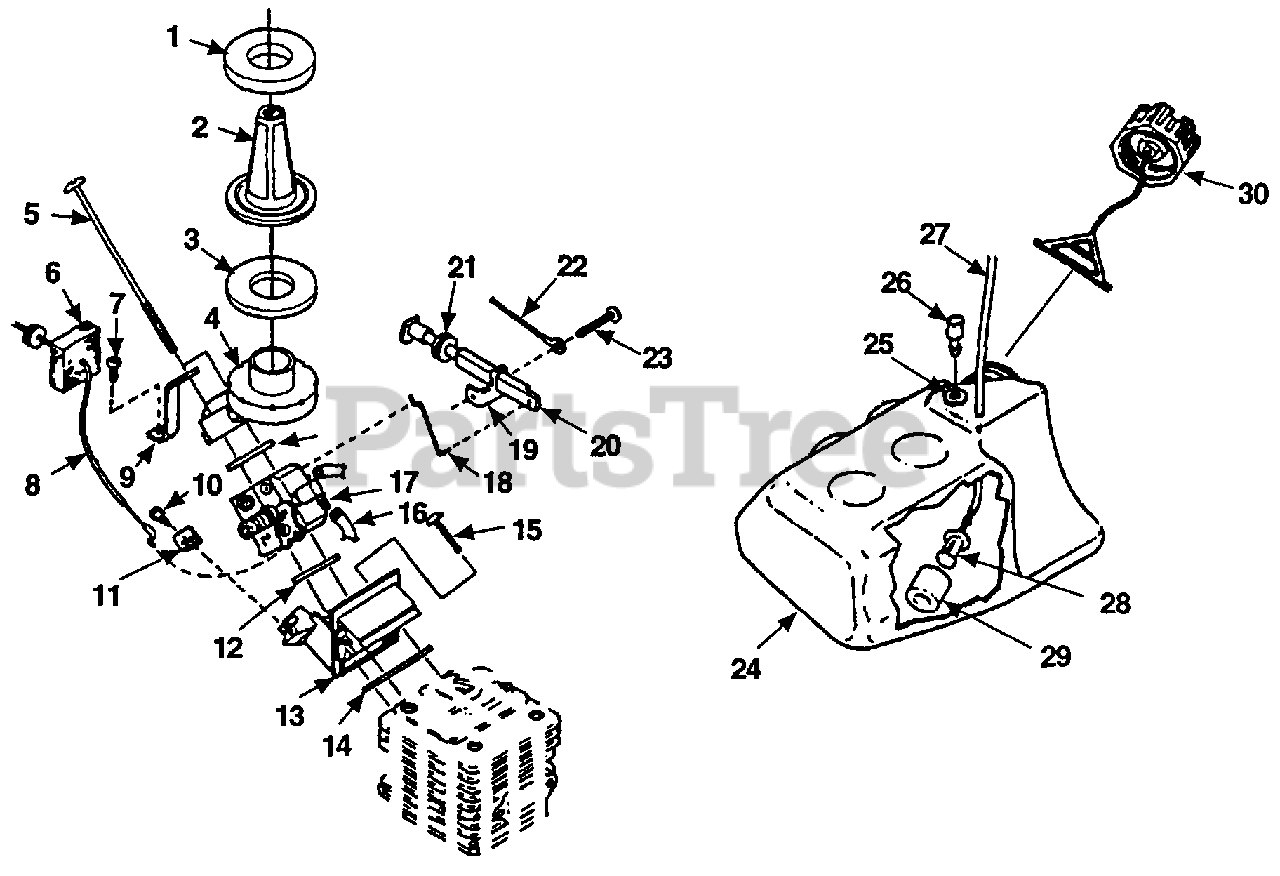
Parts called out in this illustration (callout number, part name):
1	GASKET-Foam (1/4")
2	FILTER-Screen
3	GASKET-Foam
4	ADAPTOR-Intake
5	SCREW-Truss Hd. (8-16 X 3 1/4")
6	PAD-Foam
7	SCREW-Torx (10-24 X 1/2")
8	CABLE-Throttle
9	BRACKET-Air Intake
10	SCREW-Thread Form. (6-19 X 1/2")
11	BRACKET-Cable End
12	GASKET-Carburetor
13	ADAPTOR-Intake
14	GASKET-Adaptor
15	SCREW-Pan Hd. (10-24 X 1")
16	TUBING, Pulse line (4 3/4")
17	CARBURETOR-Walbro
18	CHOKE LINK & RETAINER
19	BRACKET-Cable
20	ROD-Choke
21	GROMMET
22	GROUND WIRE
23	SCREW-Truss Hd. (10-24 X 1 1/4")
24	TANK-Fuel
25	GROMMET
26	FILTER SLEEVE (Complete)
27	TUBING-Rubber (10")
28	FILTER-Fuel
29	FILTER-Fuel
30	CAP-Tank (w/Retainer)
